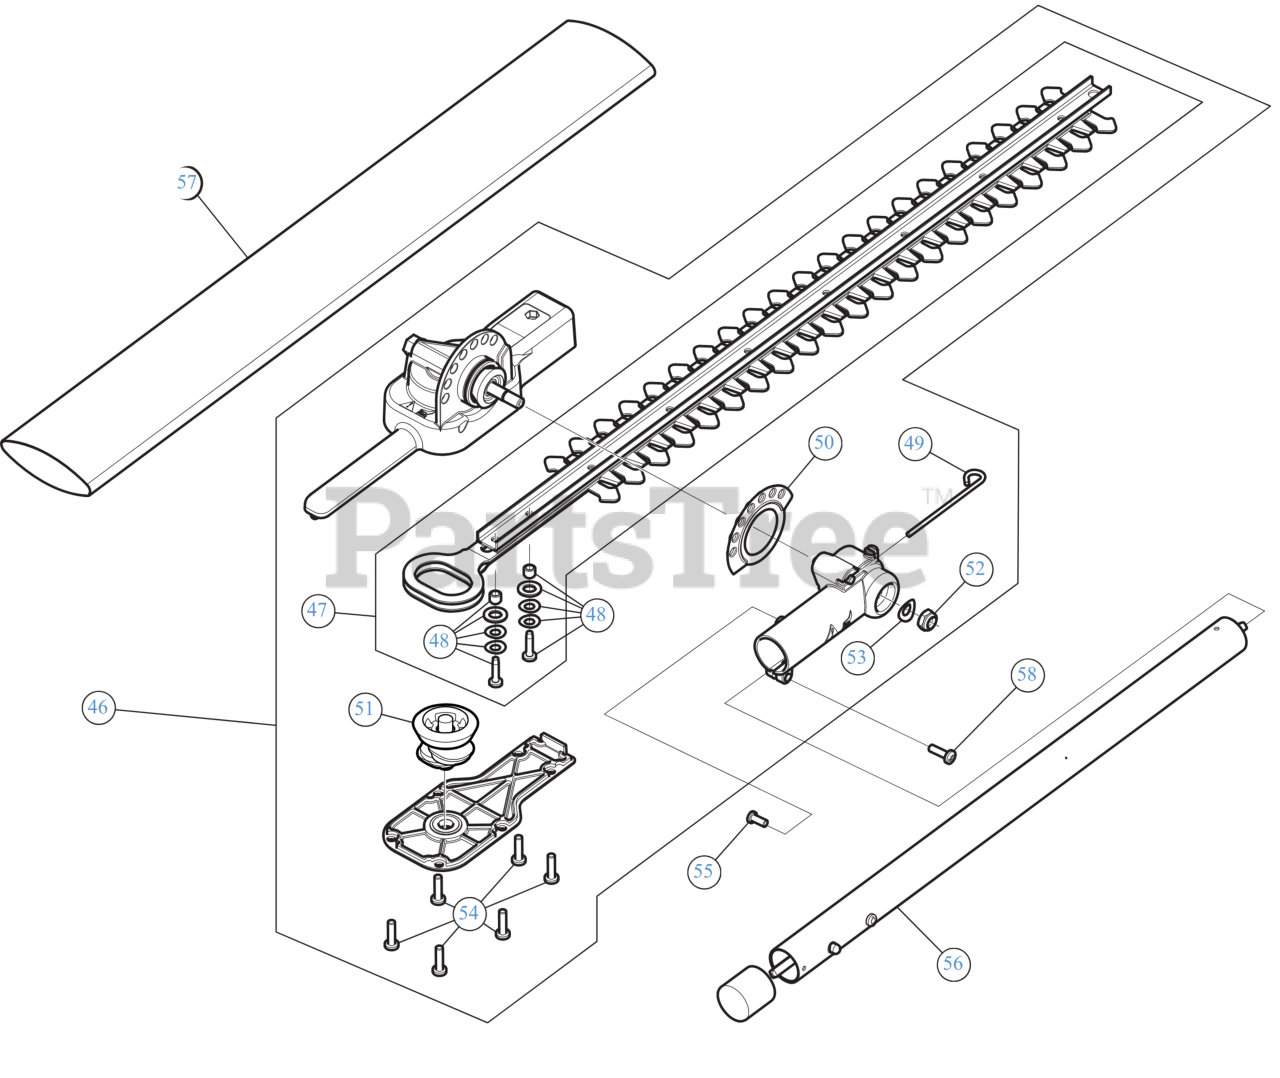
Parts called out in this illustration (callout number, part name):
46	GEARBOX ASSEMBLY
47	BLADE ASSEMBLY
48	BLADE HARDWARE
49	LOCKING LEVER PIN
50	SPACER DETENT SHM
52	NUT 5/16-24
53	SHAKE PROOF WASHER
54	SCREW - 10-24X.625 PAN HEAD
55	SCREW 8-32X.437
56	BOOM ASSEMBLY
57	BLADE COVER
58	SCR, M5 x 15.8MM
